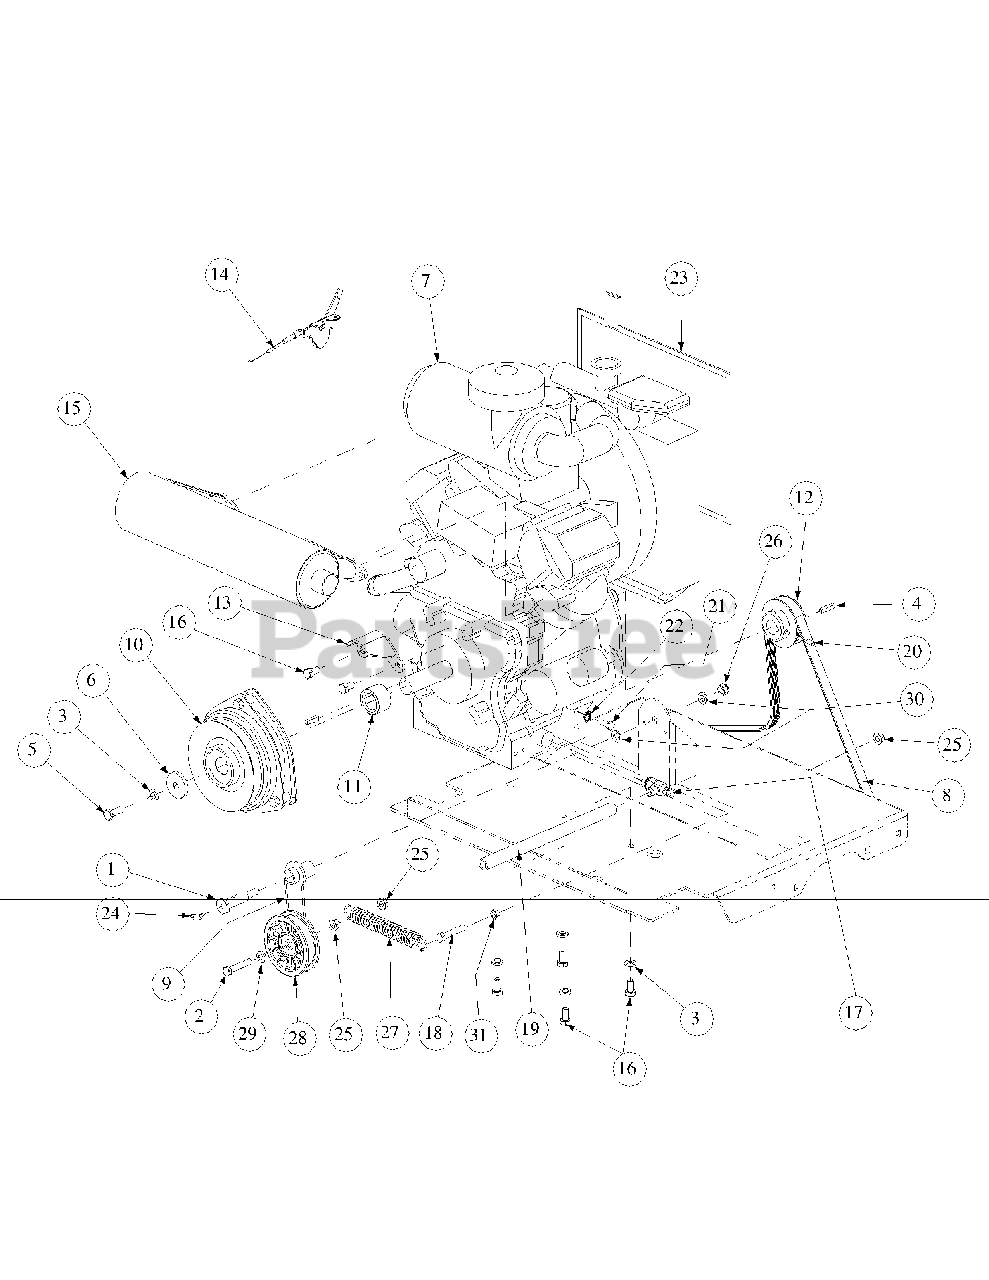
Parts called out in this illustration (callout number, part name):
1	Shoulder Screw, 7/16-14
2	Hex Cap Screw, 3/8-16 x 2.25
3	Lock Washer, 7/16
4	Key Stock, 1/4 x 1/4 x 2.00
5	Hex Head Cap Screw, M10 x 1.5, 30mm
6	Flat Washer, 7/16 ID x 1.75 OD x .25
7	29HP Digital Fuel Injection Engine, Kawasaki
8	V Belt
9	Idler Arm Assembly
10	Clutch Brake
11	Spacer, 1.75 OD x 1.135 ID x 1.125
12	Pulley, 3.05 OD x 1.0 Bore
13	Clutch Retainer Bracket
14	Throttle, Control Cable, 47.0
15	Muffler, 29HP Horizontal, Kawasaki
16	Hex Head Cap Screw, M10 x 1.5, 20mm
17	Oil Valve
18	Hex Cap Screw, 3/8-16 x 1.25
19	Oil Drain Extension Hose
20	Set Screw, 5/16-18
21	Hex Head Cap Screw, M10 x 1.25, 20mm
22	Washer, 3/8 ID, External Tooth
23	Screen, Kawasaki 29HP Radiator
24	Grease Fitting, 1/4-28 90 Degree
25	Nut, 3/8-16, Hex Flange Lock
26	Nut, 7/16-14, Nylock
27	Extension Spring, 1.0 OD x 5.00
28	Idler Pulley, 3.5 OD
29	Washer, 3/8
30	Washer, .469 ID x .875 OD x .105
31	Jam Nut, 3/8-16
